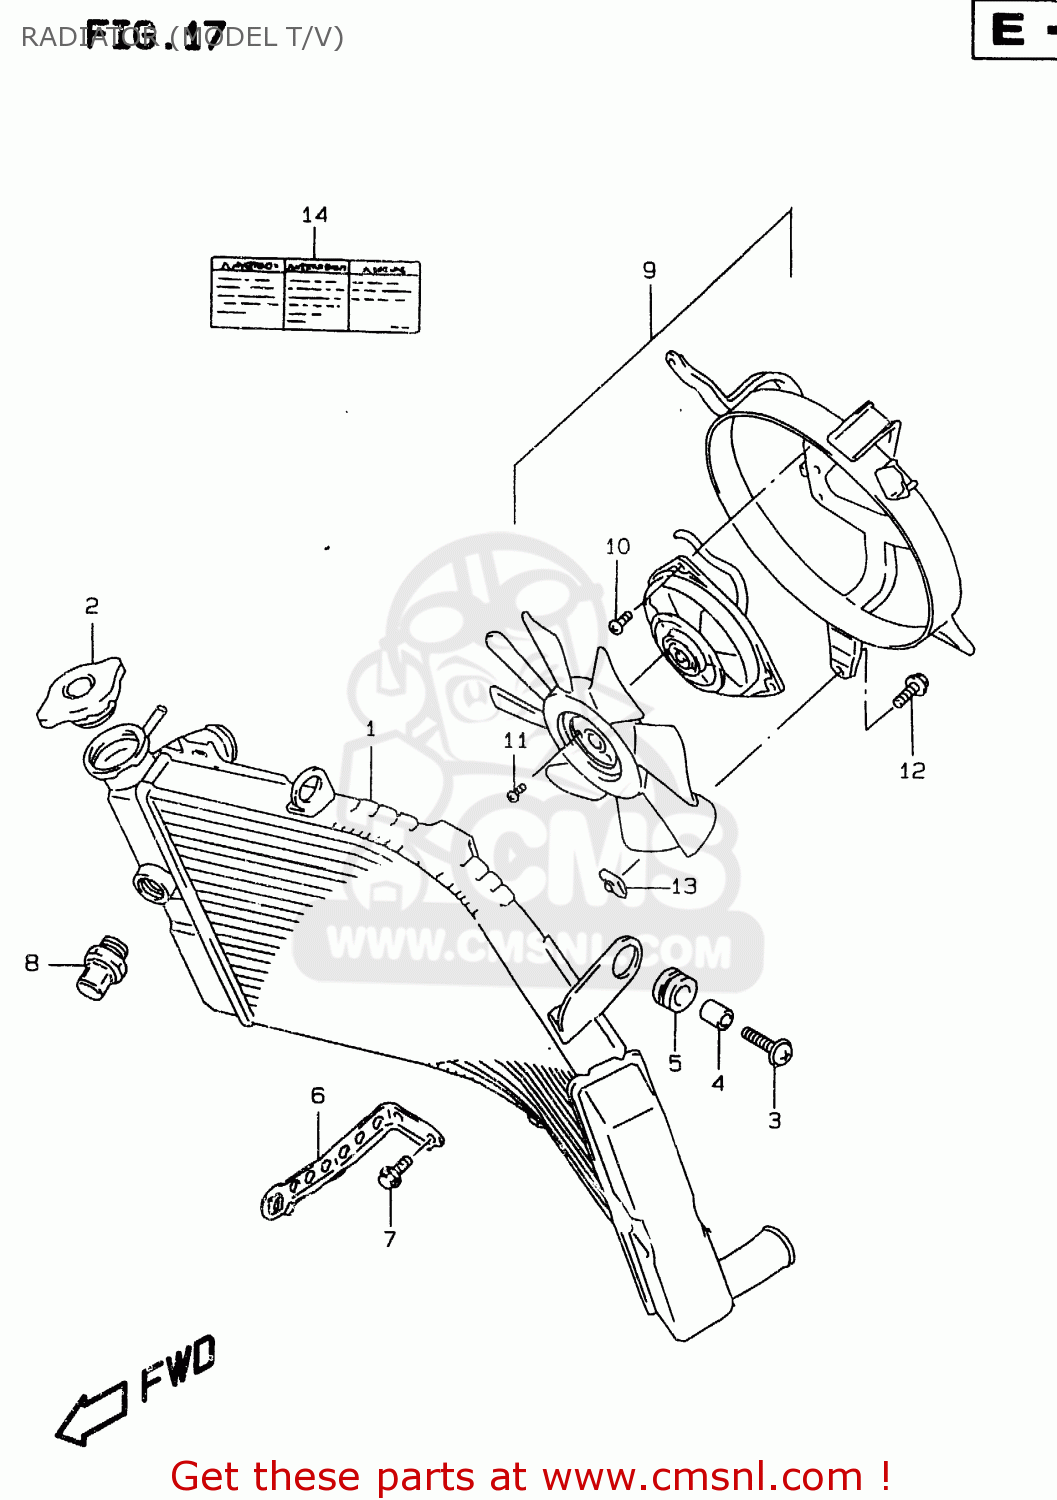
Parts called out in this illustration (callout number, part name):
1	RADIATOR ASSY,WATER
2	CAP,RADIATOR
3	BOLT 6X20
4	SPACER(6.5X10X12)
5	CUSHION
6	BRACKET,RADIATOR LWR
7	BOLT
8	SWITCH,RADIATOR FAN
9	FAN ASSEMBLY,RADIATOR
10	SCREW
11	SCREW 4X6
12	BOLT
13	NUT,RADIATOR COVER
14	LABEL, COOLING FAN
